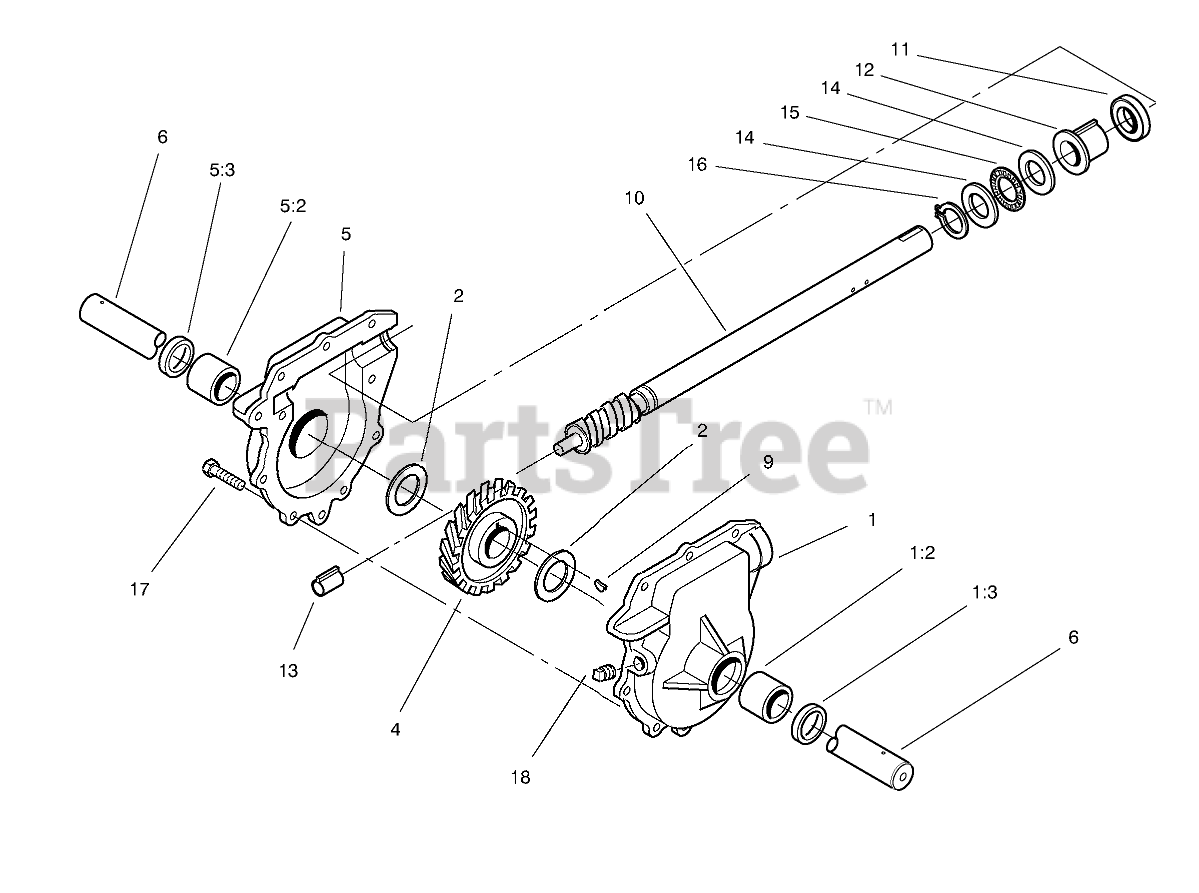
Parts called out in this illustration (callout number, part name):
1	LH AUGER GEARCASE ASM
1:2	BUSHING
1:3	SEAL-OIL
2	WASHER-THRUST
4	GEAR-HELICAL
5	RH AUGER GEARCASE ASM
5:2	BUSHING
5:3	SEAL-OIL
6	SHAFT-AUGER
9	KEY-WOODRUFF
10	SHAFT-IMPELLER
11	SEAL-OIL
12	BUSHING-INPUT
13	BUSHING-WORM
14	WASHER-THRUST
15	BEARING-THRUST
16	RING-RETAINING, Ext
17	SCREW-HWH
18	PLUG-PIPE, SQH
